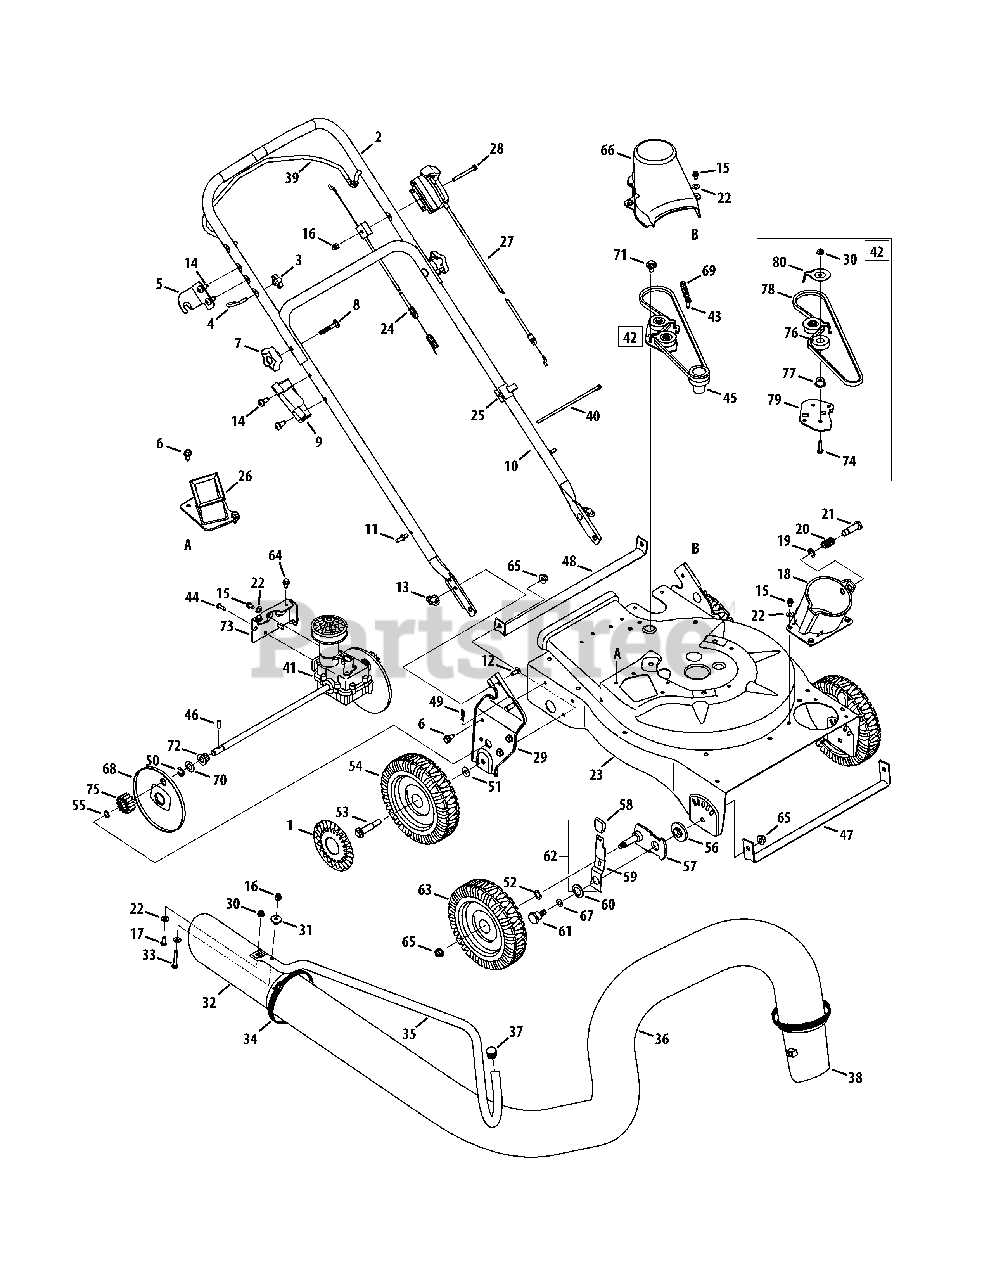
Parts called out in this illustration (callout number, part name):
1	Hub Cap
2	Upper Handle
4	Eye Bolt
5	Upper Handle Bracket
6	Hex Cap Screw 5/16-12 x.750
7	Handle Knob 5/16-18
8	Carriage Bolt
9	Nozzle Handle Clip
10	Lower Handle
11	Studs
12	Carriage Screw 1/4-20 x.75
13	Wing Nut 1/4-20
14	TT Screw, 5/16-18 x .750
15	Screw, 1/4-20 x .500
16	Cap Lock Nut, 1/4-20
17	Hex Cap Screw 1/4-20 x.620
18	Hose Base Adapter Assembly
19	E Ring.500 Dia
20	Compression Spring
21	Clevis Pin
22	Flat Washer.271 ID x.630 OD
23	Upper Flail Housing
24	Drive Control Cable
25	Cable Guide
26	Chipper Chute Assembly
27	Speed Control Cable
28	Hex Screw, 1/4-20 x 2.50
29	Handle Bracket Ass’y RH
29	Handle Brkt Ass’y LH
30	Flange Lock Nut, 1/4-20
31	Spacer
32	Hose Nozzle
33	Hex Cap Screw 1/4-20 x 2.625
34	Adjustment Clamp
36	Vacuum Hose
37	Handle Plug
38	Hose Adapter
39	Drive Control
40	Cable Tie
41	Transmission Assembly
42	Idler Assembly (Incl. Ref.# 74-80)
43	Shoulder Screw, #12-24 x .30 x .46
44	Screw, #12-16 x .750
45	Impeller Hub
46	Dowel Pin
47	Front Wheel Support Brace
48	Rear Wheel Support Brace
49	Cotter Pin
50	E-Ring
51	Flat Washer, .406 x .875 x .105
52	Wave Washer.531 ID x.781 OD
53	Shoulder Screw 3/8-16
54	Rear Wheel
55	Snap Ring
56	Height Adjustment Bearing
57	Pivot Arm Assembly
58	Height Adjustment Knob
59	Spring Lever
60	Bell Washer.760 ID x.25 OD
61	Shoulder Screw,.750 x.500
62	Height Lever Assembly
63	Front Wheel
64	Screw, 1/4-20 x .625
65	Flange Lock Nut, 3/8-16
66	Belt Cover
67	Thrust Washer.375 ID x.70 OD
68	Wheel Cover
69	Extension Spring,.375 x 2.95
70	Flat Washer,.508ID x1.00OD x.020
71	Shoulder Screw,.560 x.165
72	Drive Axle Bushing
73	Transmission Mounting Bracket
74	Screw, 1/4-20 x 1.00
75	Spur Gear - RH
75	Spur Gear - LH
76	Ball Bearing
77	Flange Spacer,.260 x.659 x.517
78	Belt, 3/8 x 32.5
79	Idler Bracket
80	Belt Keeper
